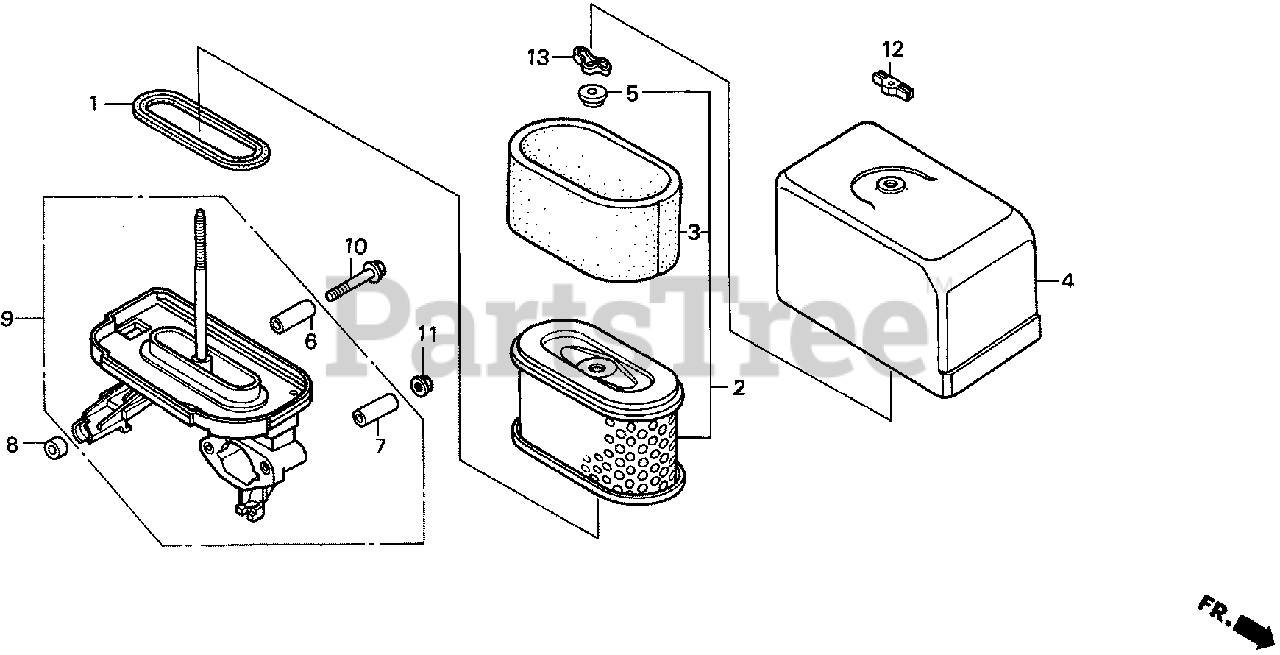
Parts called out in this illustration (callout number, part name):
1	GASKET, ELBOW
2	ELEMENT, AIR CLEANER (METAL BASE)
3	FILTER (OUTER)
4	COVER, AIR CLEANER (DUAL)
5	GROMMET, AIR CLEANER
6	COLLAR, AIR CLEANER
7	COLLAR, AIR CLEANER
8	SPACER, AIR CLEANER ELBOW
9	ELBOW, AIR CLEANER
10	BOLT, FLANGE (6X45) (CT200)
11	NUT, CAP (6MM)
11	NUT, FLANGE (6MM)
12	WINGNUT (6MM) (BLACK)
13	NUT, TOOL BOX SETTING
